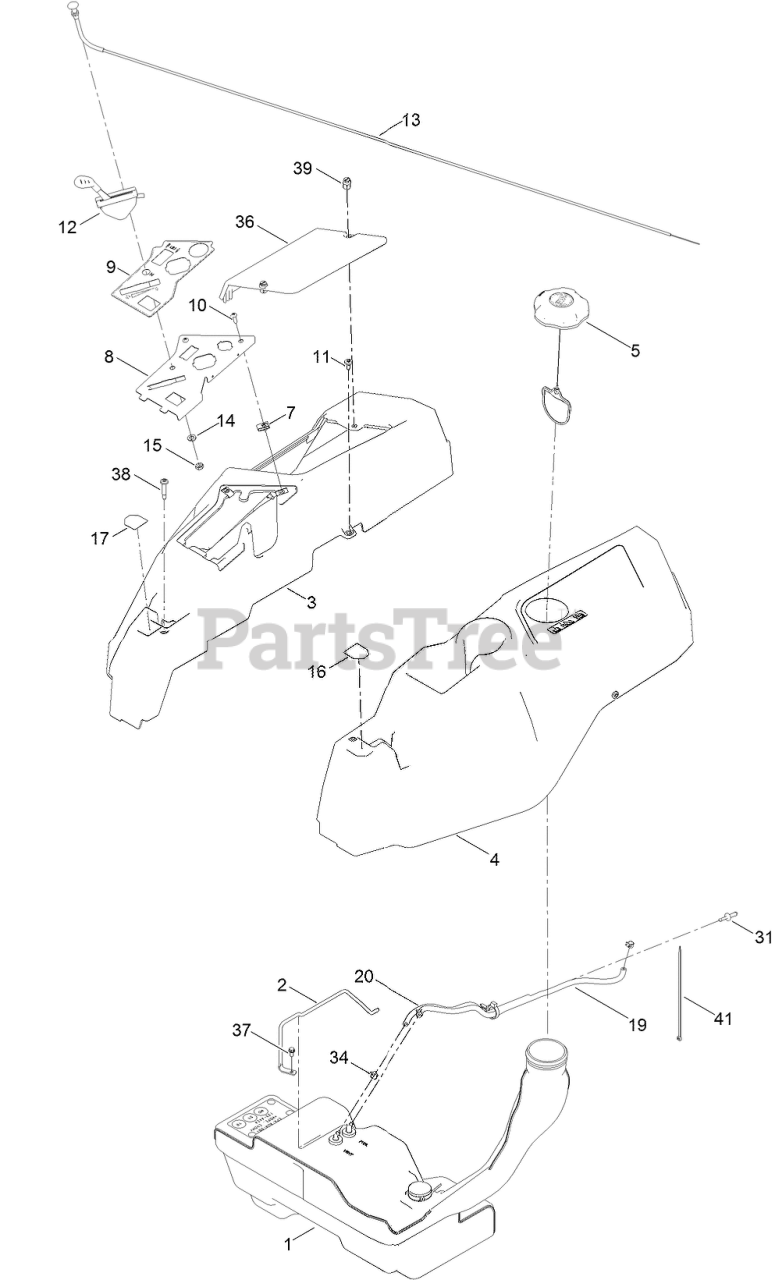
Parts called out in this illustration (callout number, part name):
1	FUEL TANK ASM
2	ROD-HOLD DOWN
3	POD-RH
4	POD-LH
5	CAP-FUEL, RATCHETING
8	PANEL-CONTROL
9	DECAL-CONTROL W/CHOKE
10	SCREW-PRH
11	SCREW-SHOULDER
12	CABLE-THROTTLE
13	CABLE-CHOKE
14	WASHER-LOCK
15	NUT-HJ
16	DECAL-LEVER, CONTROL (LH)
17	DECAL-LEVER, CONTROL (RH)
19	HOSE-FUEL
20	HOSE-FUEL
31	ADAPTOR-ORIFICE
34	CLAMP-HOSE
36	COVER-BATTERY
37	SCREW-HWH
38	SCREW-SHOULDER
39	FASTENER
41	TIE-CABLE
